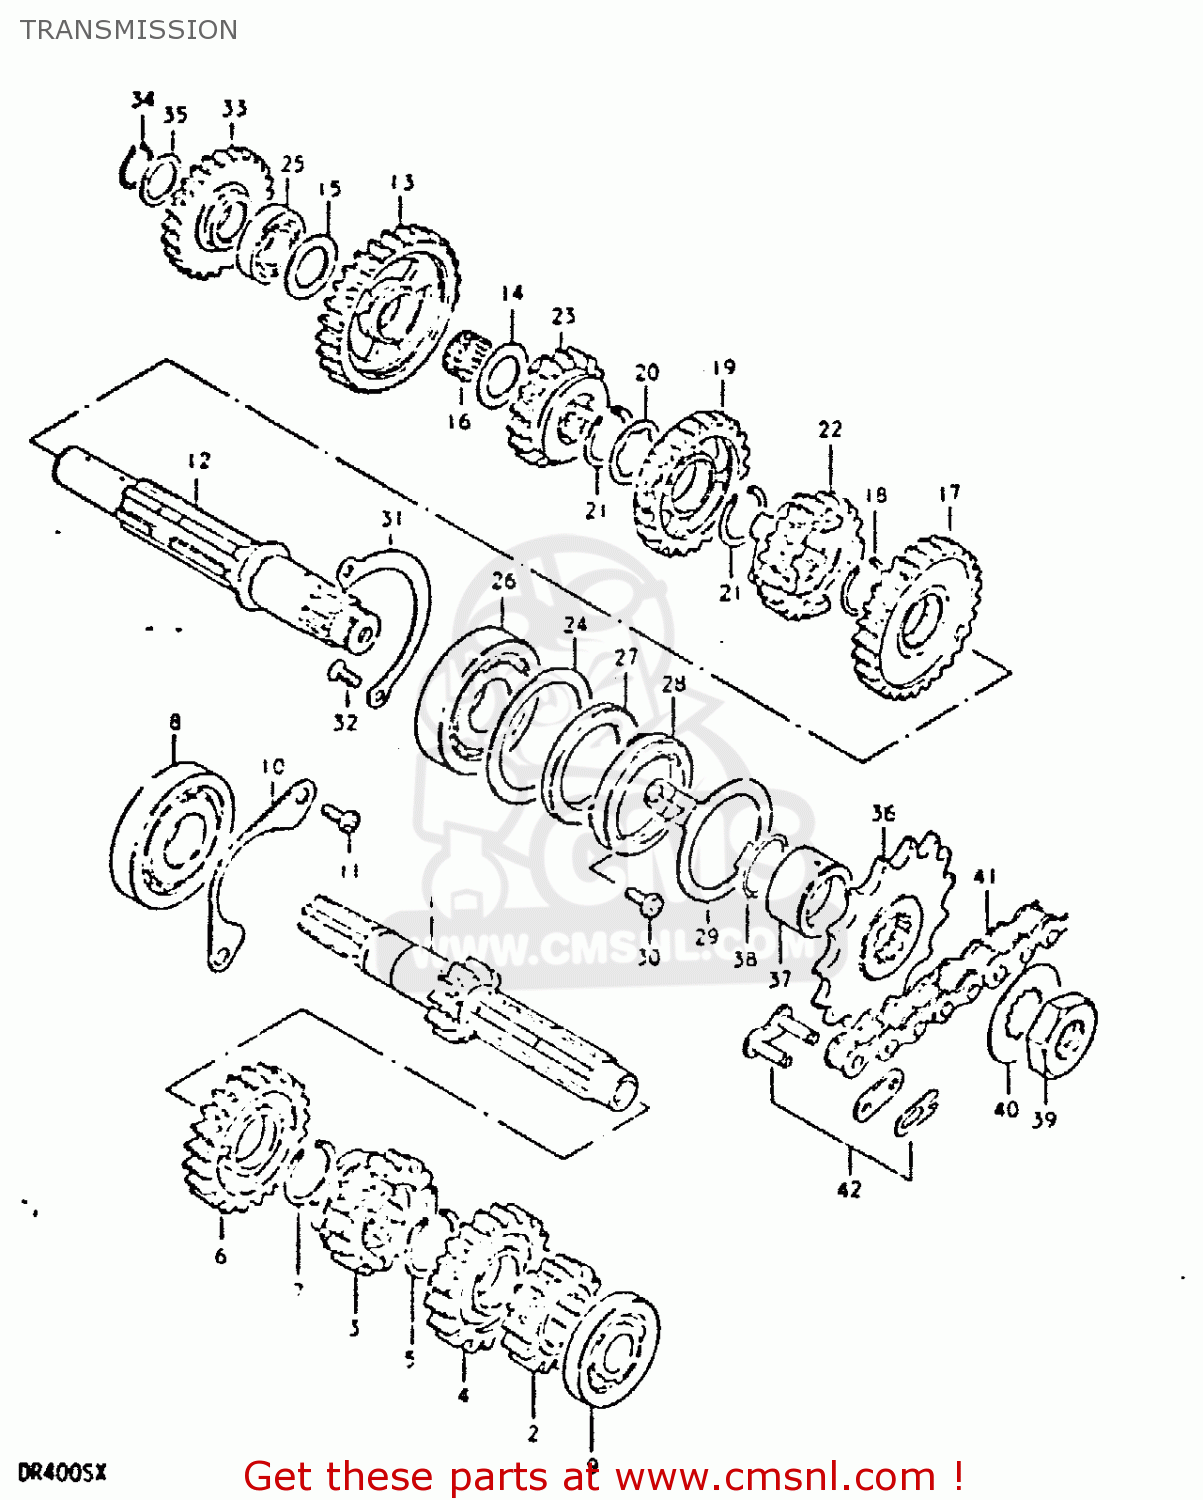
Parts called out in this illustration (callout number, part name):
1	SHAFT,COUNTER
2	GEAR,SECOND DRIVE
3	GEAR,THIRD DRIVE
4	GEAR,FOURTH DRIVE
5	CIRCLIP
6	GEAR,FIFTH DRIVE
7	CIRCLIP
8	BEARING
9	BEARING
10	PLATE,COUNTERSHAFT BEARING
11	SCREW 6X12
12	SHAFT,DRIVE
13	GEAR,FIRST DRIVEN
14	WASHER
15	WASHER
16	BEARING(17X21X9.8)
17	GEAR,SECOND DRIVEN
18	CIRCLIP
19	GEAR,THIRD DRIVEN
20	WASHER,LOCK
21	CIRCLIP
22	GEAR,FOURTH DRIVEN
23	GEAR,FIFTH DRIVEN
24	WASHER
25	BEARING(17X36X12)
26	BEARING(22X56X16)
27	OIL SEAL (30X47X5)
28	SEAL,OIL(30X47X7)
29	PLATE,DRIVESHAFT OIL
30	SCREW 6X12
31	RETAINER,DRIVE SHAFT BEARING
32	SCREW
33	GEAR,KICK STARTER IDLER(NT:25)
34	CIRCLIP
35	WASHER
36	SPROCKET,ENGINE(NT:16)
37	SPACER,ENGINE SPROCKET
38	O RING(D:2.5,ID:21)
39	NUT
40	WASHER,LOCK
41	CHAIN ASSEMBLY,DRIVE
42	JOINT ASSEMBLY,CHAIN
